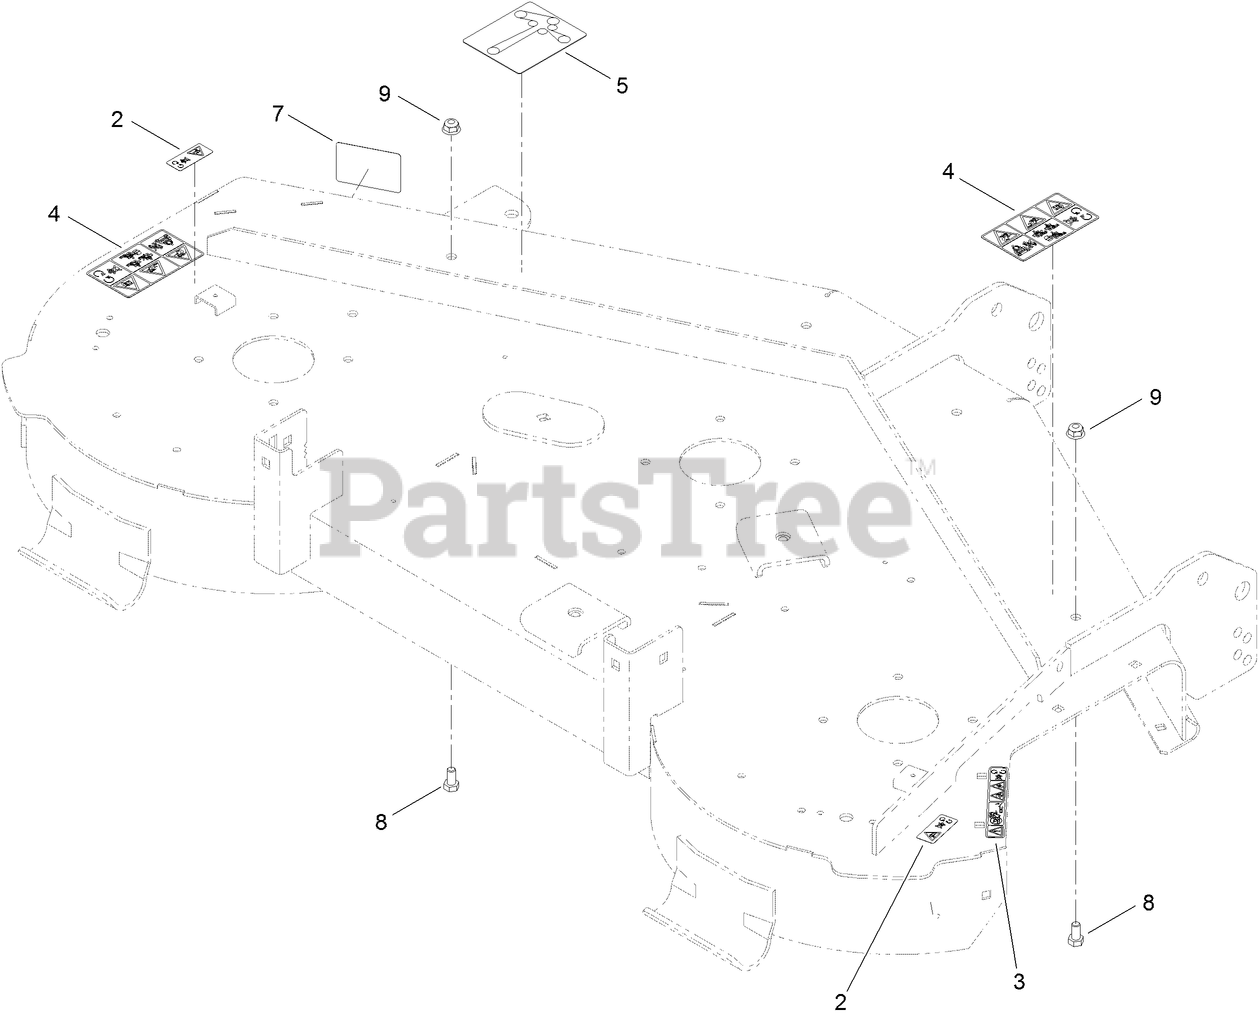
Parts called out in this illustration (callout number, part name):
2	DECAL-DANGER
3	DECAL-DANGER
4	DECAL-DANGER
5	DECAL-ROUTING, BELT
7	DECAL-SCALP, ANTI
8	SCREW-HH
9	NUT-HF, NI
